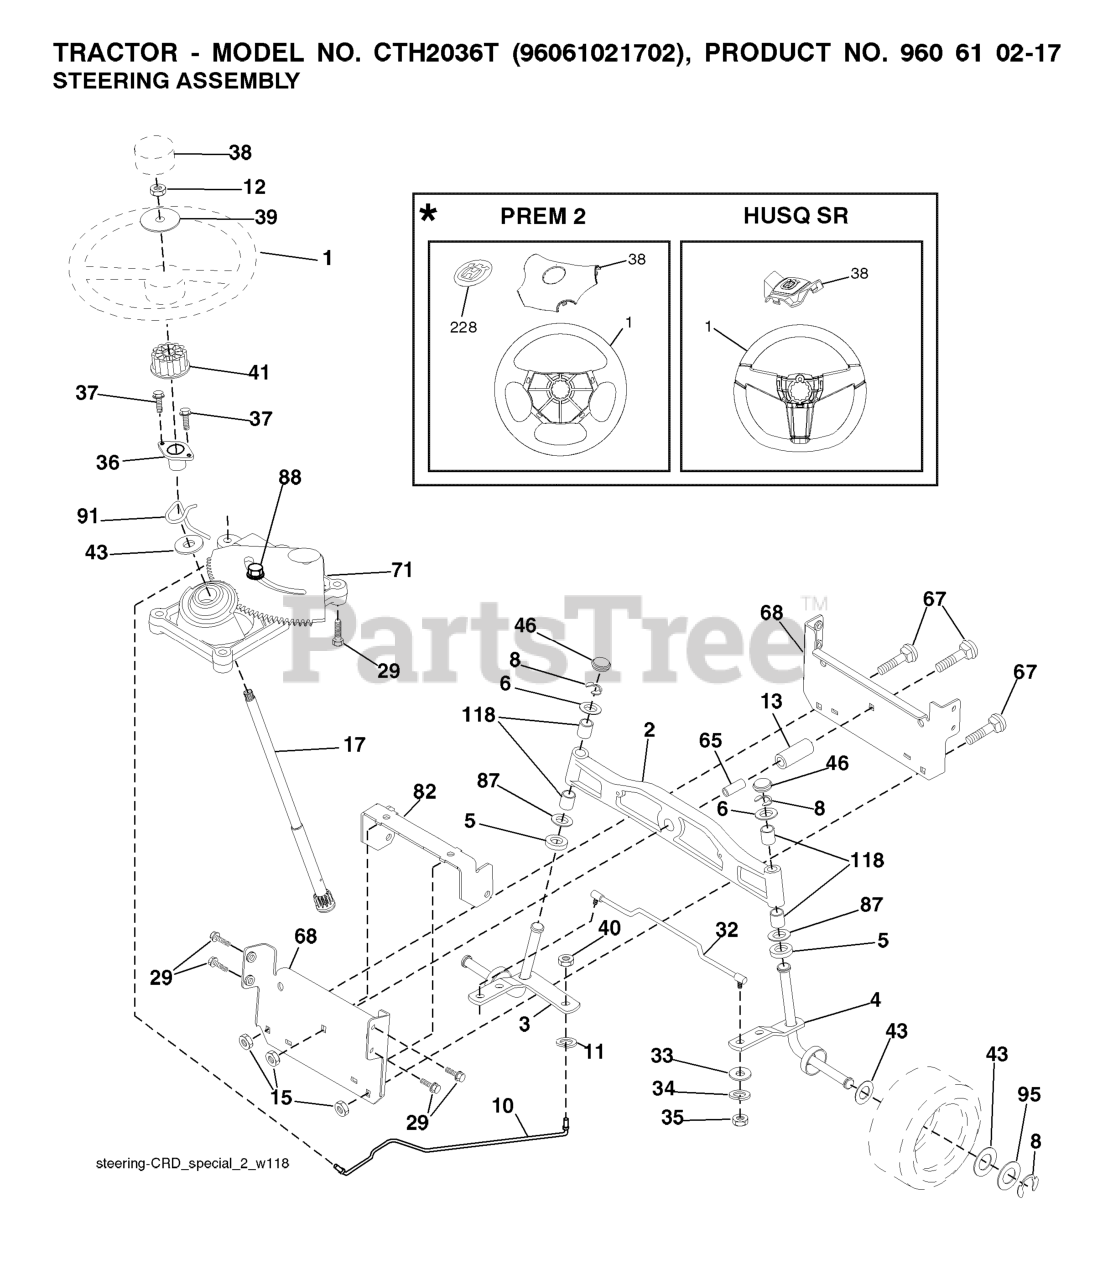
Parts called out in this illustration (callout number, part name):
1	RP WHEEL.STEER.HUSQ.PREM.OVMLD
2	AXLE ASSY FRONT
3	SPINDLE.ASM.LH.15"TIRES
4	SPINDLE.ASM.RH.15"TIRES
5	THRUST WASHER
10	DRAGLINK.15".TIRES.2001
11	WASHER, LOCK 3/8
12	NUT.HEX.1/2-20
13	TUBE, PIVOT AXLE
15	NUT
17	SHAFT ASM STRG
29	SCREW, 3/8-16X3/4
33	WASHER M
34	WASHER.LOCK.HVY.HLCL.SPR.5/16
35	NUT, CROWNLOCK
36	BUSHING, STRG. BLK
37	SCREW.TT.#10-32X.5.3/8.FLANGE
38	RP INSERT.CAP.WHL.STRG.HUSQ.
39	WASHER 9/16"ID, 2 3/8"OD
40	NUT CROWNLOCK 3/8-24
41	ADAPTER, WHEEL STNG..
46	CAP.SPINDLE.BLACK
65	SPACER.BRACE.AXLE
67	BOLT CARRIAGE
68	BRACE.AXLE.15"TIRES
71	STEERING ASM
82	BRACKET.SUSP.CHASSIS.FRONT.15
87	WASHER, FLAT .781 X 1 1/2"
88	BOLT, SHOULDER 7/16-20
91	CLIP.STEERING
95	WASHER.HARDENED
118	BUSHING, AXLE CAST
